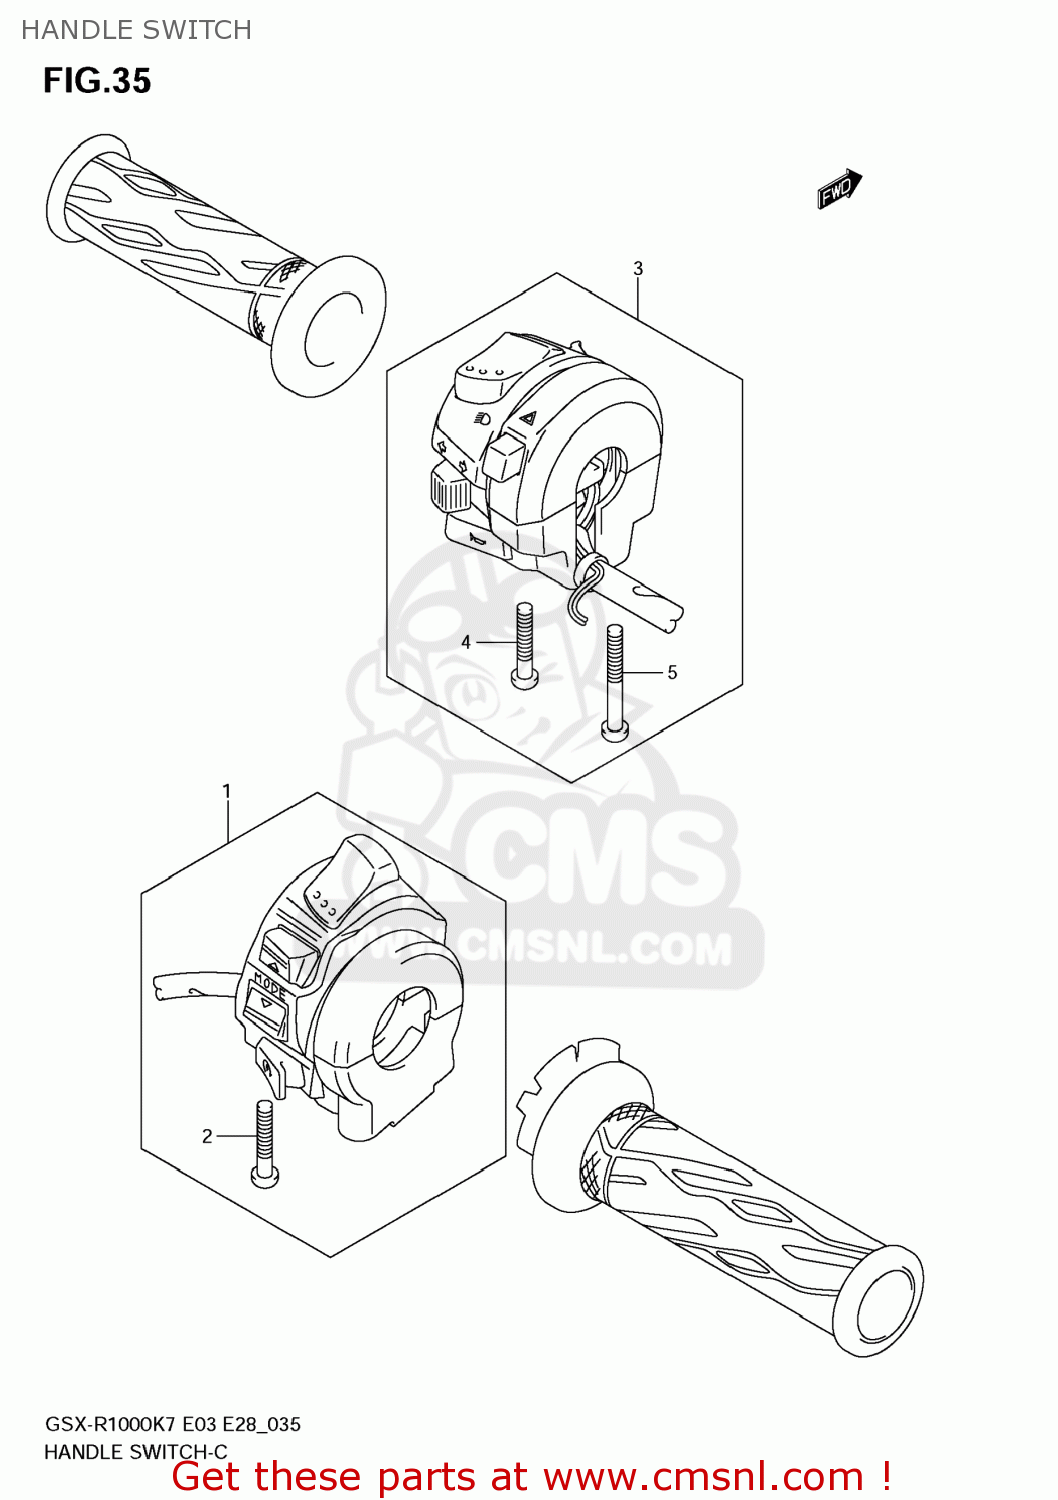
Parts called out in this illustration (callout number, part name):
1	SWITCH ASSY,HA
2	SCREW
3	SWITCH ASSY,HA
4	SCREW
5	SCREW
